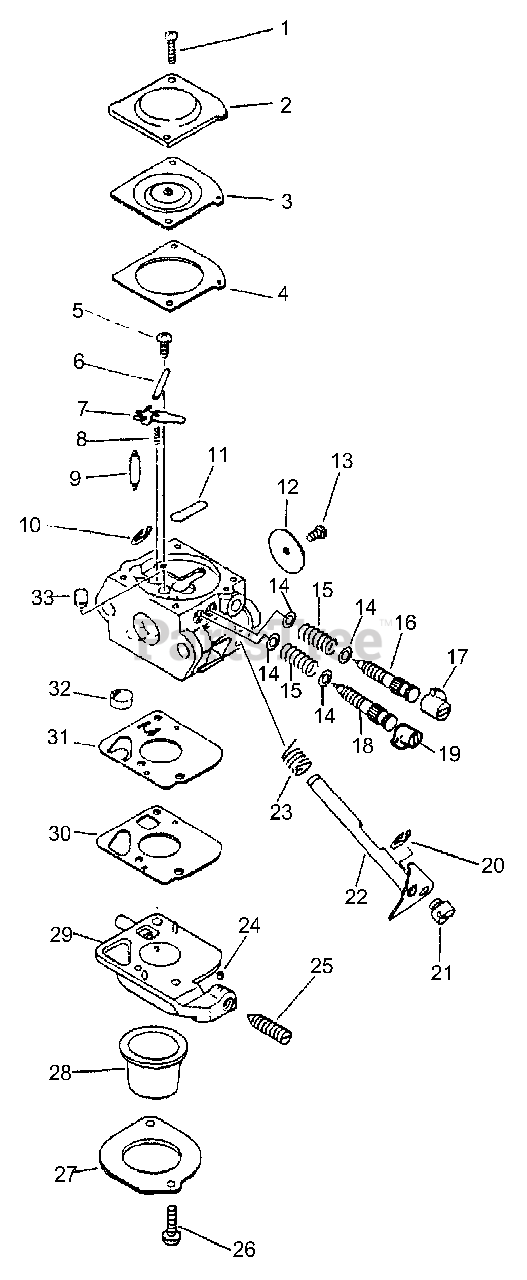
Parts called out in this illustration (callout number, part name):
2	COVER, METERING DIAPHRAGM
3	DIAPHRAGM, METERING
4	GASKET, METERING
6	PIN, METERING LEVER
7	LEVER, METERING
8	SPRING, METERING LEVER
9	VALVE, NEEDLE
11	PLUG, WELCH
12	VALVE, THROTTLE
15	SPRING, NEEDLE
16	NEEDLE, MIXTURE
17	CAP, LIMITER - WHITE
18	NEEDLE, HIGH SPEED
19	CAP, LIMITER - RED
22	SHAFT, THROTTLE
23	SPRING, THROTTLE RETURN
24	PIECE, FRICTION
25	SCREW, IDLE ADJUST
27	RETAINER
28	BULB, PURGE
29	BODY ASSY, PURGE
30	GASKET, PUMP
31	DIAPHRAGM, PUMP
32	STRAINER
33	NOZZLE, CHECK VALVE
33	REPAIR KIT, CARBURETOR
33	GASKET / DIAPHRAGM KIT
